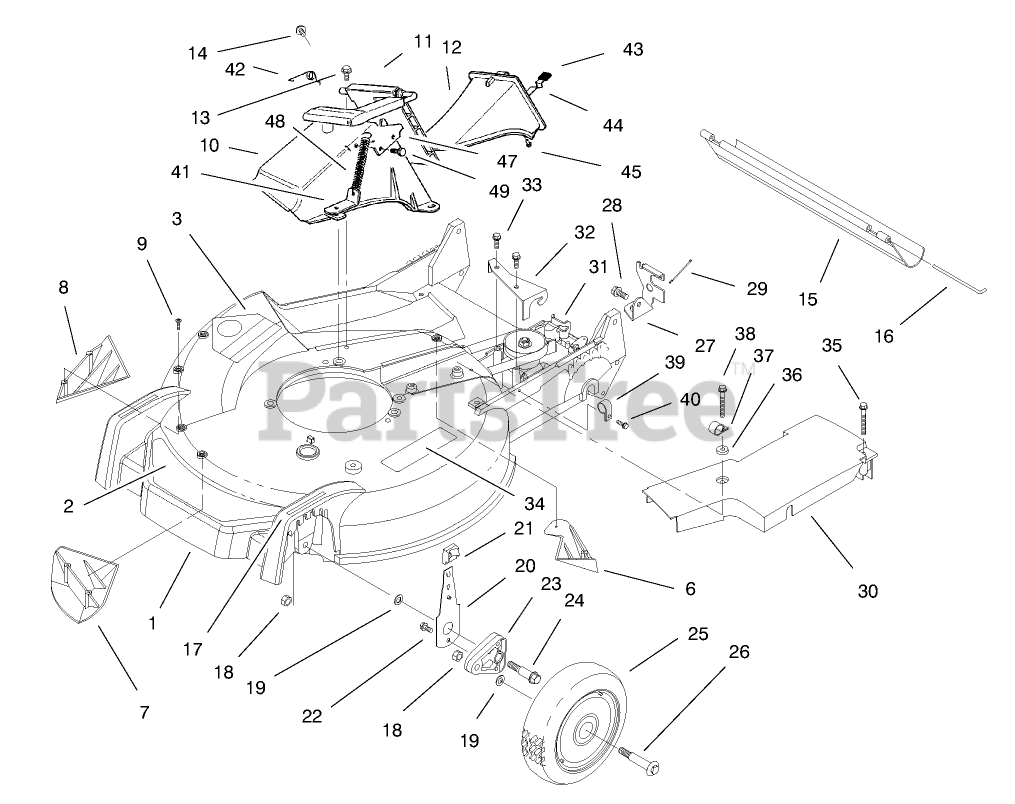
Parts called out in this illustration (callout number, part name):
2	DECAL - DECK
3	DECAL-DANGER
6	KICKER-REAR
7	KICKER-FRONT
8	KICKER-RH
9	SCREW-PPH
10	TUNNEL-DISCHARGE
11	DISCHARGE DOOR ASM
12	DISCHARGE PLUG ASM
13	SCREW-HWH
14	SCREW AND WASHER ASM
16	ROD-SHIELD
18	NUT-LOCK
19	WASHER
20	FRONT SPRING ARM ASM
21	KNOB-ARM
22	SCREW-HWH
24	BOLT-SHOULDER
25	WHEEL AND TIRE ASM
28	SCREW-HWHTF
29	RETAINER-CABLE
30	COVER - BELT
31	GEARCASE ASM
33	SCREW-HWHTF
35	SCREW-HWH
36	WASHER
37	CLAMP-CABLE
38	SCREW-SPECIAL
39	CLAMP-CABLE
40	SCREW-HWH
41	BRACKET-SPRING
42	RETAINER-DOOR
43	GRIP-LATCH
44	LATCH-PLUG, DISCHARGE
45	RIVET-HEAD, FLAT
47	LATCH-PLATE
48	SPRING-DOOR
49	SCREW-PLASTITE
